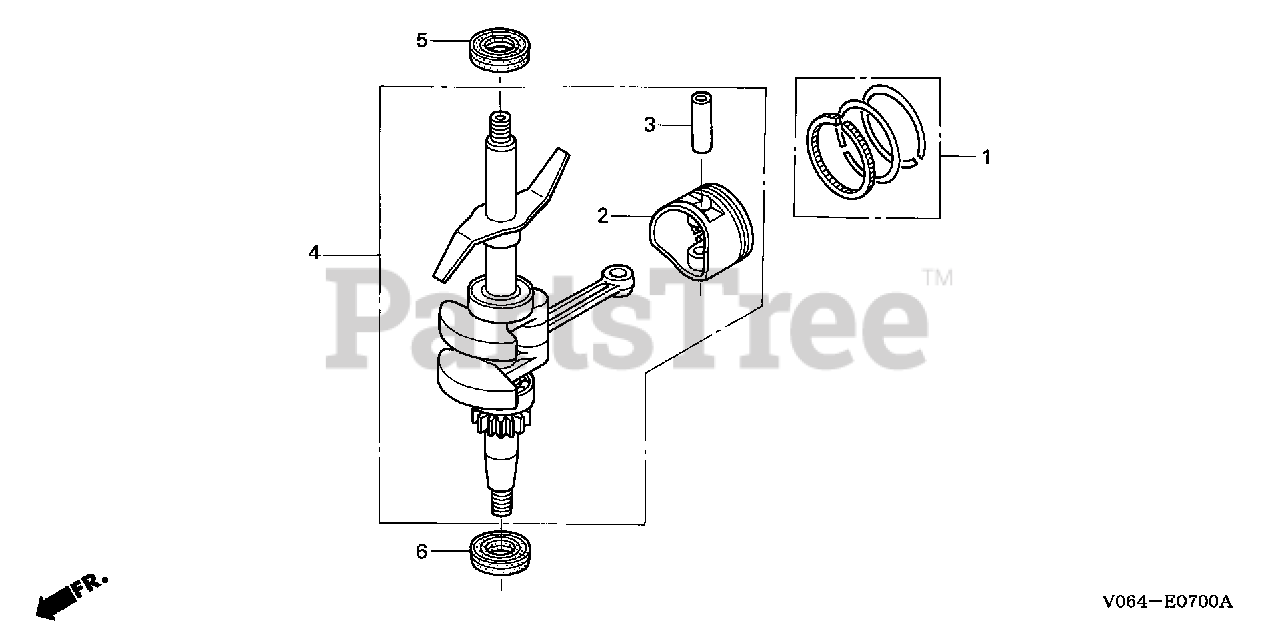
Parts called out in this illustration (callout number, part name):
1	RING SET, PISTON
3	PIN, PISTON
4	CRANKSHAFT
5	OIL SEAL (12X25X6)
6	OIL SEAL (15X25X6)
